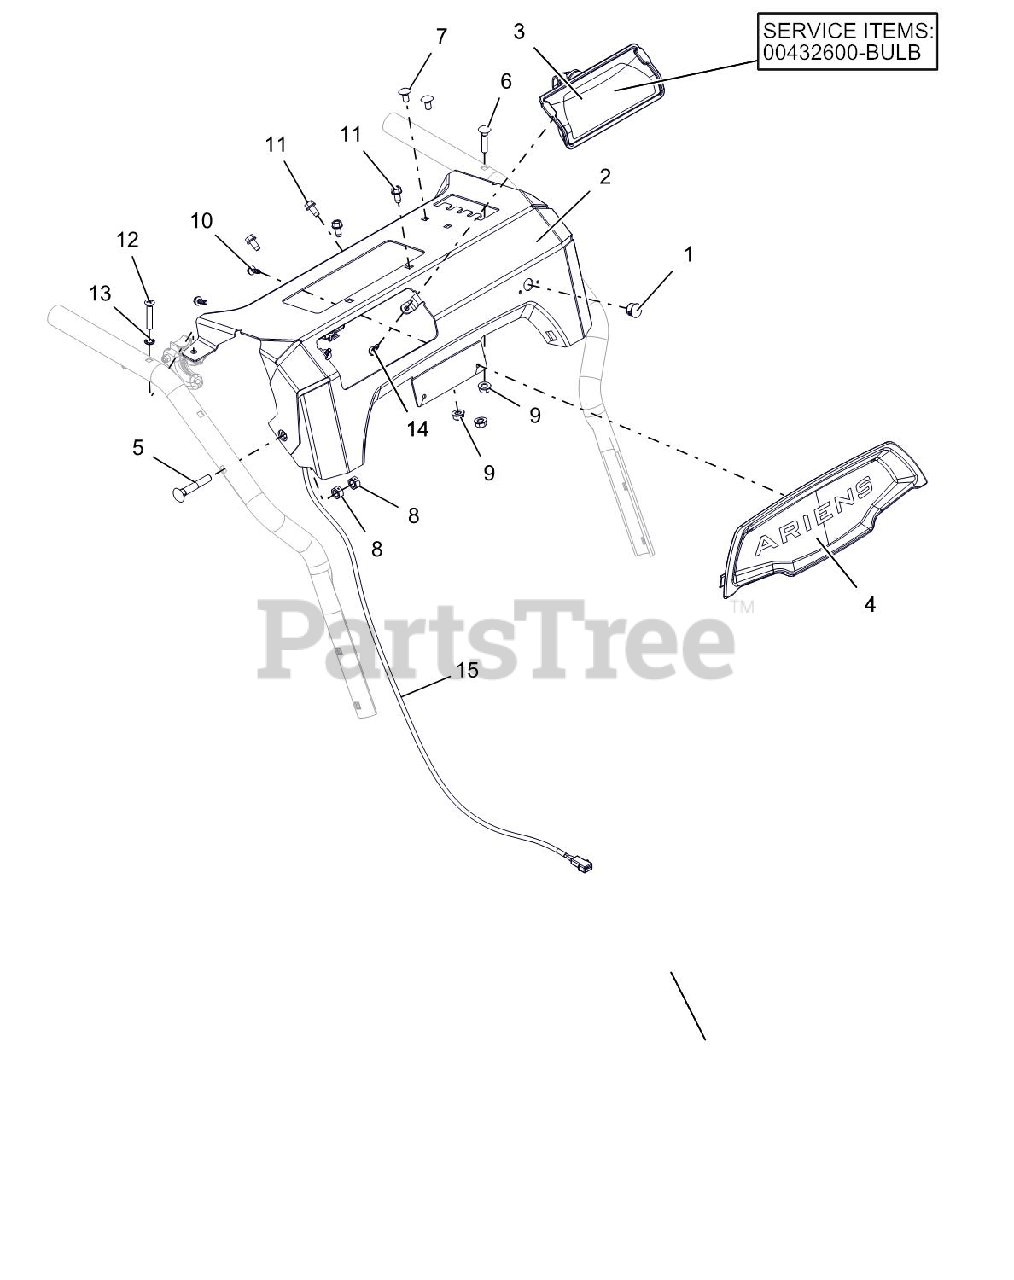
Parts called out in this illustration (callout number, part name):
1	HOLE PLUG, PLASTIC .56 HOLE
2	CTRL PANEL W/DECAL-COMP TRACK
3	BULB, LIGHT-HALOGEN 20W
3	HEADLIGHT ASY, HALO 20W 2SHOT
4	BEZEL, DASH - ARIENS SM DASH
5	BLT-RDHDXLSQNK .31-18X2.0 G5YZ
6	BLT-RDHDXLSQNK.25-20X1.25 G5ZC
7	@BLT-RDHDSQNK .25-20X.50 G5YZ
8	@NUT-LK-CTR .31-18 YWZC
9	@NUT-LK-TOP-FLG .25-20 YWZC
10	SCR-TAP #10X.50 BOSS INDHXHD
11	SCR-TAP .25-20X.50 HWH TR YWZ
12	SCR-MCH .25-20X1.50 OVAL HD
13	WSHR-LK-INT .250 TH TYA
14	SCR-TAP #10X.50 BOSS INDHXHD
15	HARNESS, LIGHT - COMPACT
